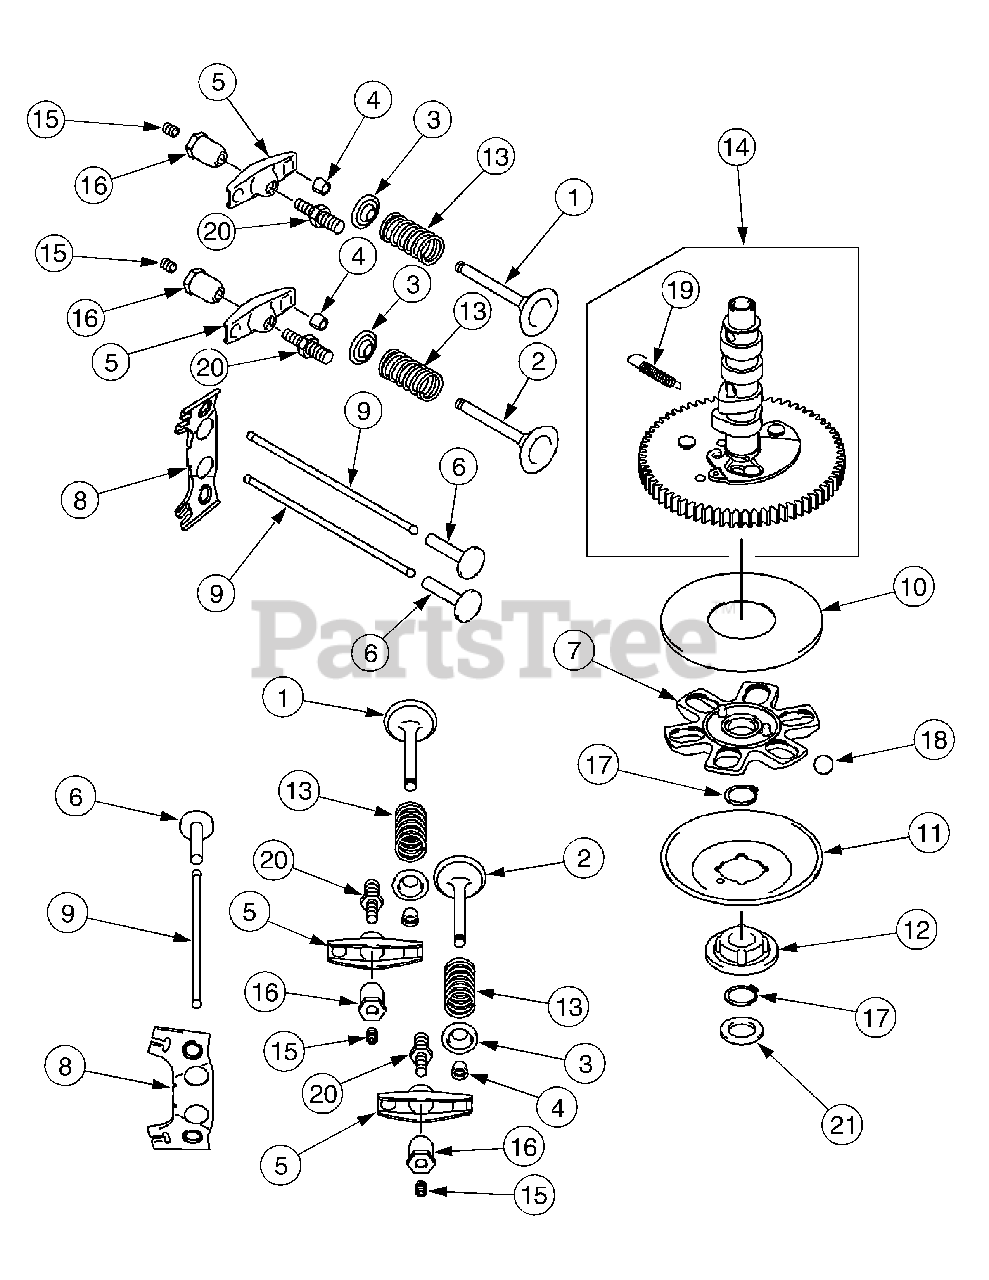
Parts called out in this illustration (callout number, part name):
1	Valve, Intake
2	Valve, Exhaust
3	Retainer, Valve Spring
5	Arm, Rocket
11	Plate, Governor
12	Sleeve
13	Spring, Valve
14	Camshaft, Complete
17	Ring, Snap
18	Ball
19	Spring
